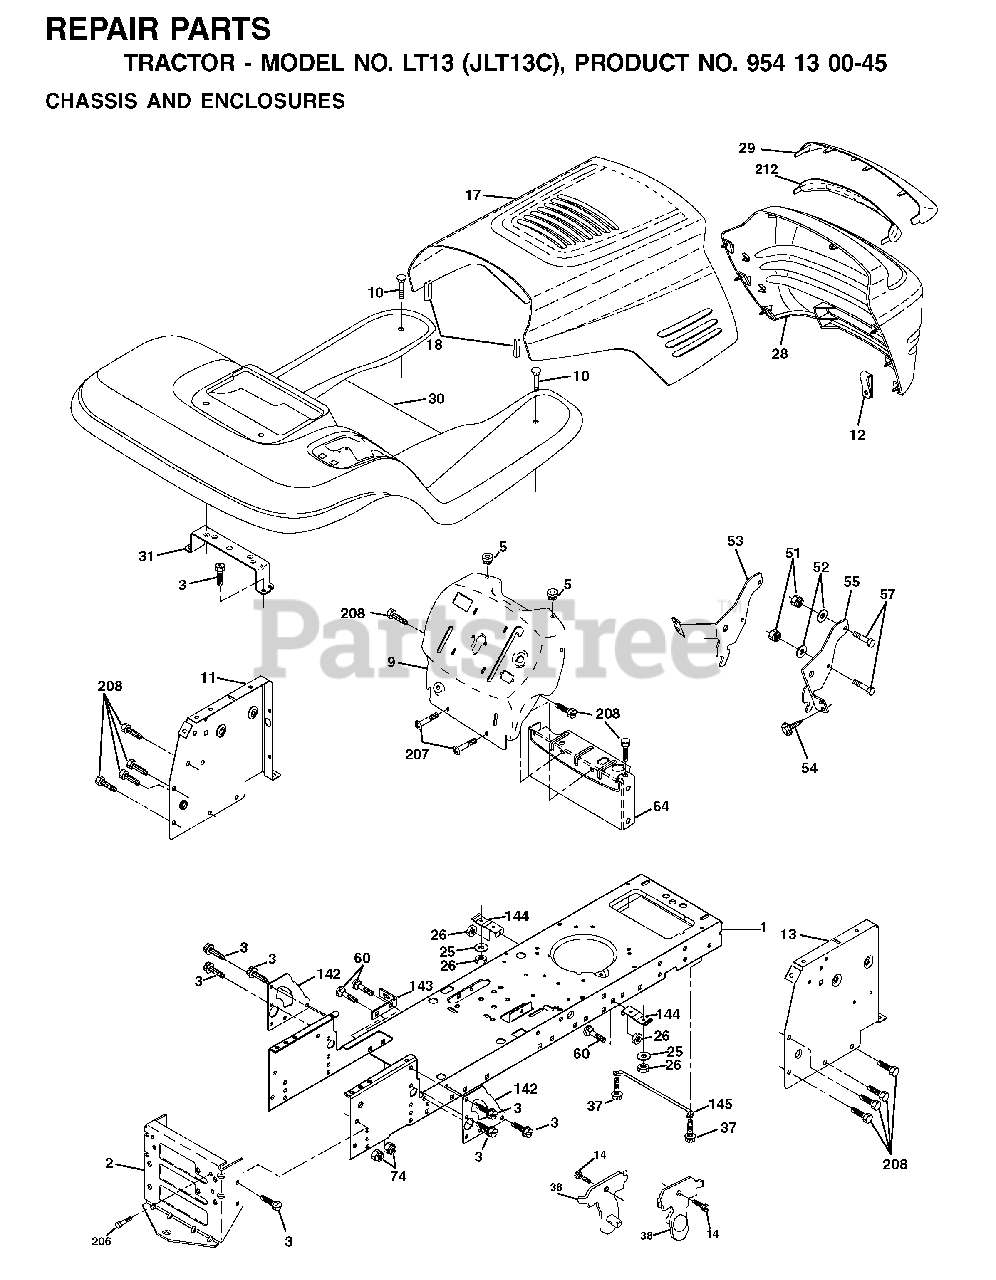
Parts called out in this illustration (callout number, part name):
1	CHASSIS STAMPING
2	DRAWBAR, 12GA
3	SCREW 3/8-16X3/4
5	BUMPER.RUBBER.HOOD
10	BOLT D
11	PANEL DASH LH
13	DASH PANEL ASM.
18	BUMPER HOOD T
25	WASHER
26	NUT
38	BRACKET.ASM.PIVOT.MOWER.REAR
51	LOCKNUT
57	BOLT
64	DASH LOWER
74	LOCKNUT
142	PLATE REINFORCEMENT
143	BRACKET, SWAY BAR
144	BRKT, FOOT REST
145	ROD PIVOT CHASSIS/HOOD
206	SHOULDER BOLT 5/16-18TT
207	SCREW, 5/16-18 X 1/2
208	SCREW 3/8-16X1/2
